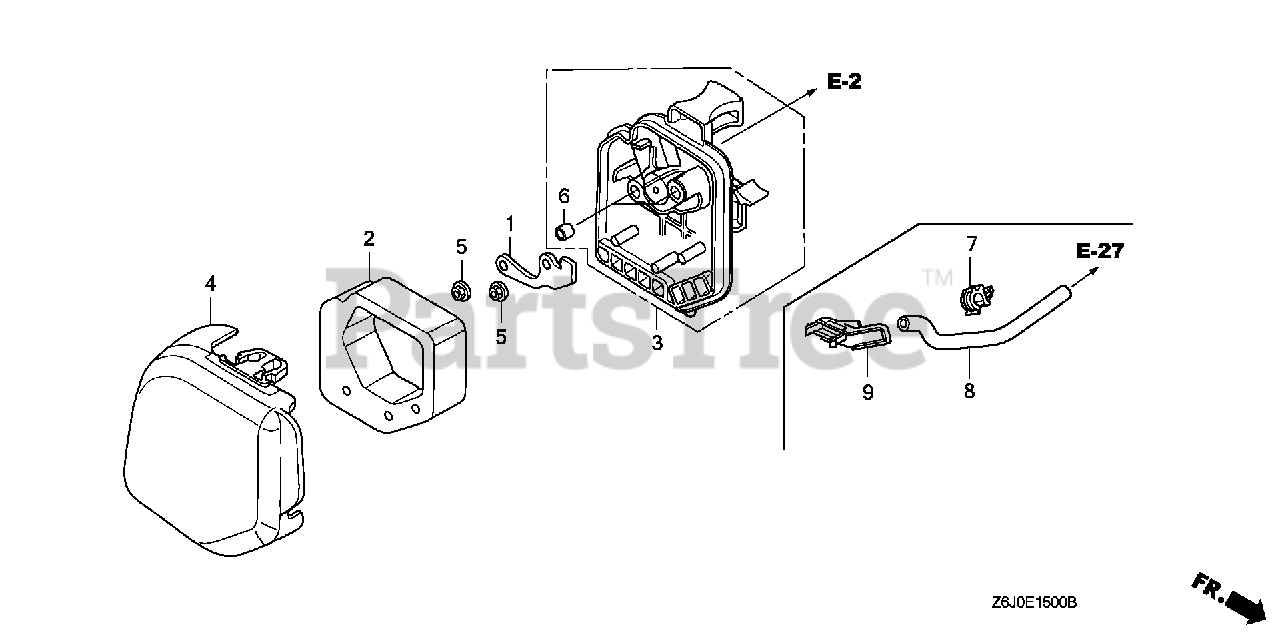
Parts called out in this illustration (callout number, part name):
1	PLATE, OIL TRAP
2	ELEMENT, AIR CLEANER
3	HOUSING, AIR CLEANER
4	COVER, AIR CLEANER
5	NUT, FLANGE (5MM)
6	COLLAR, AIR CLEANER
